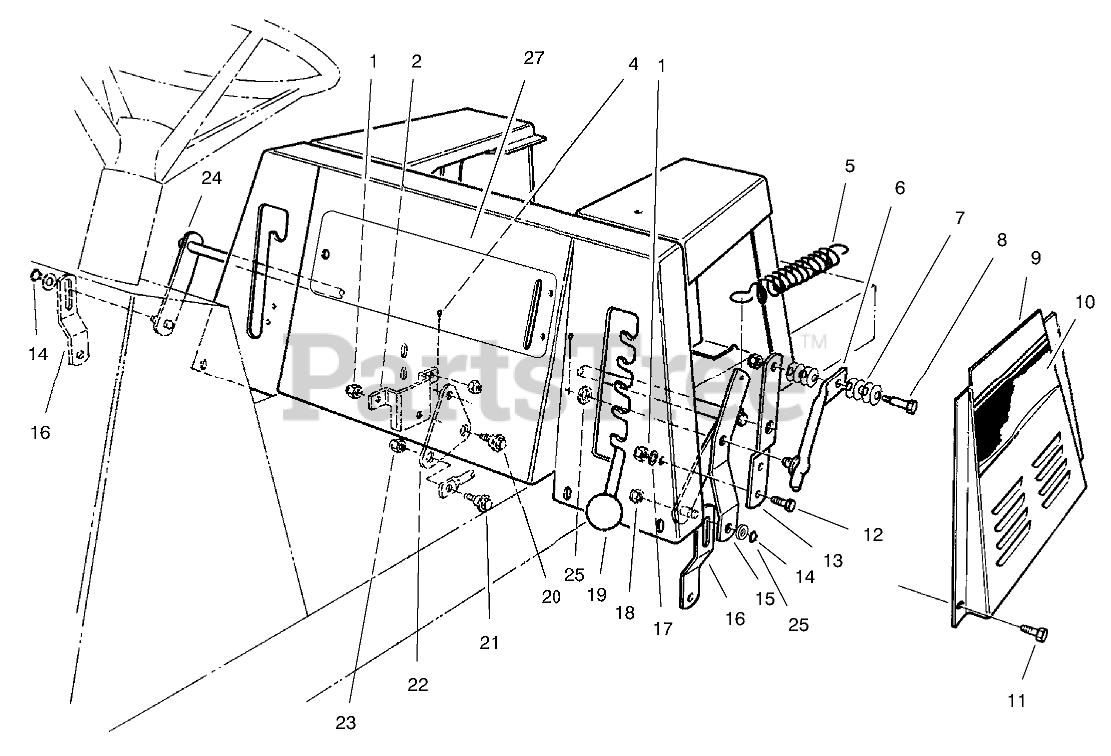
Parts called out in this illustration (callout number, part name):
1	NUT-LOCK, NI
2	BRKT-B.CRANK MTG
4	PIN-COTTER
5	SPRING-EXTENSION
6	HOC LEVER WA (BLACK)
7	WASHER-BELLEVILLE
8	BOLT-SHOULDER
9	PANEL-LH SEAT BASE
10	DECAL - SIDE
11	SCREW-HH
12	SCREW-HH
13	BRKT-HOC SUPT
14	RING-RETAINING
15	Bracket-H.O.C., Engage
16	LINK-SUSP
17	WASHER-PLAIN
18	NUT-LOCK, NI
20	SCREW-SHOULDER
21	SCREW-SHOULDER
22	BELLCRANK
23	NUT-HEX
24	HOC LEVER WA (BLACK)
25	WASHER-FLAT
27	DECAL-CONTROL PANEL,INTL
